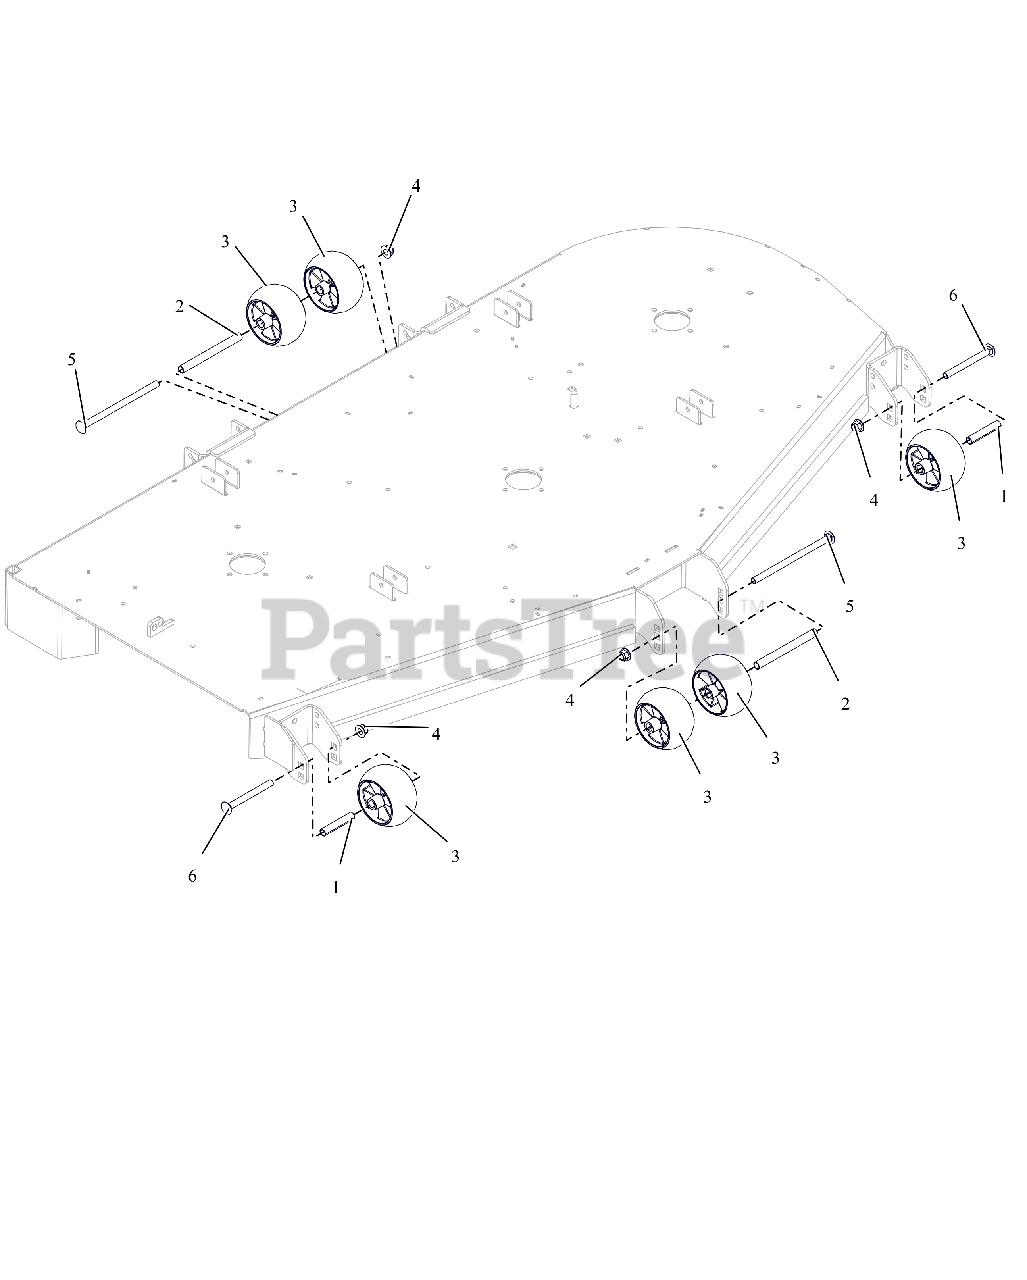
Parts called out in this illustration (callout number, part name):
1	SPACER, .510X.625X3.35
2	SPACER, .510X.625X6.50
3	ANTI-SCALP WHEEL - 5X3 CTR
4	NUT,NYL-FLG .50-13 GF ZCC
5	BLT, RHSN .50-13X8.50 G5 ZCC
6	BLT, RHSN .50-13X5.00 G5 ZCC
